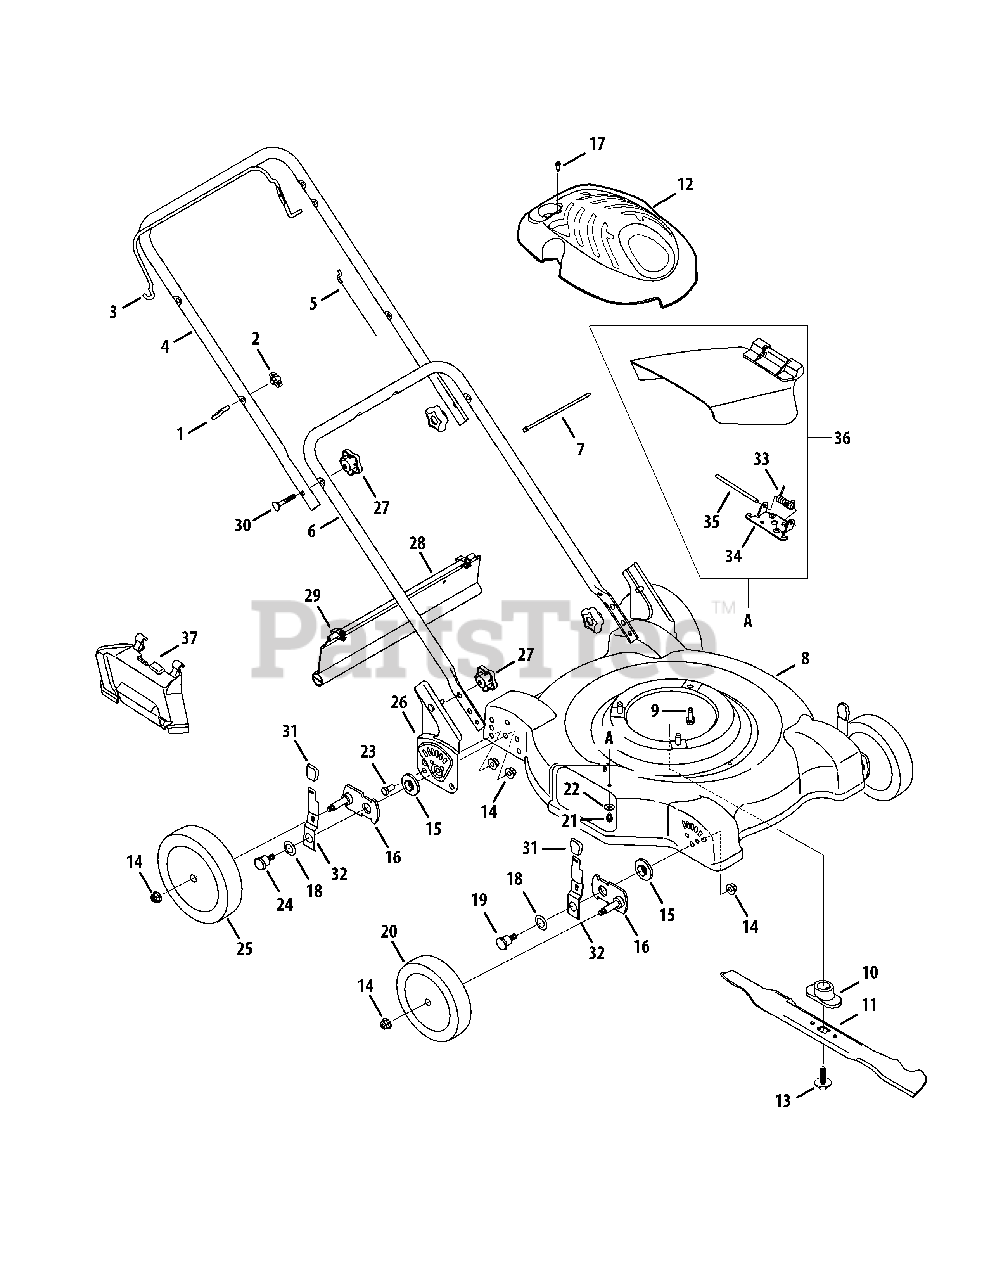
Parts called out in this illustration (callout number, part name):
1	Eye Bolt
2	Wing Nut
3	Blade Control Handle
4	Upper Handle
5	Control Cable
7	Cable Tie
8	Deck Assembly, 22"
9	TT Screw, 3/8-16 x 1.0
10	Blade Adapter
11	Mulching Blade, 22"
11	Standard Blade, 22"
12	Engine Shroud
13	Screw, 3/8-24 x 1.50
14	Lock Nut, 3/8-16
15	Height Adjuster Bearing
16	Pivot Arm
17	Screw, HL, #12-16 x 1.00
18	Bell Washer, .760 OD x 1.25 OD
19	Shoulder Screw
20	Front Wheel, 7 x 1.8, Bar
21	TT Screw, 1/4-20 x .5
22	Bell Washer, .265 ID x .75 OD
23	Screw, 3/8-16 x .75
24	Shoulder Screw
25	Rear Wheel, 8 x 1.8, Bar
26	Handle Bracket Assembly, RH
26	Handle Bracket Assembly, LH
27	Star Knob
28	Trail Shield
29	Hinge Clip
30	Carriage Bolt, 5/16-18 x 2
31	Knob
32	Lever
33	Torsion Spring
34	Chute Hinge
35	Hinge Pin
36	Hinged Chute Deflector Ass’y.
37	Mulching Baffle
